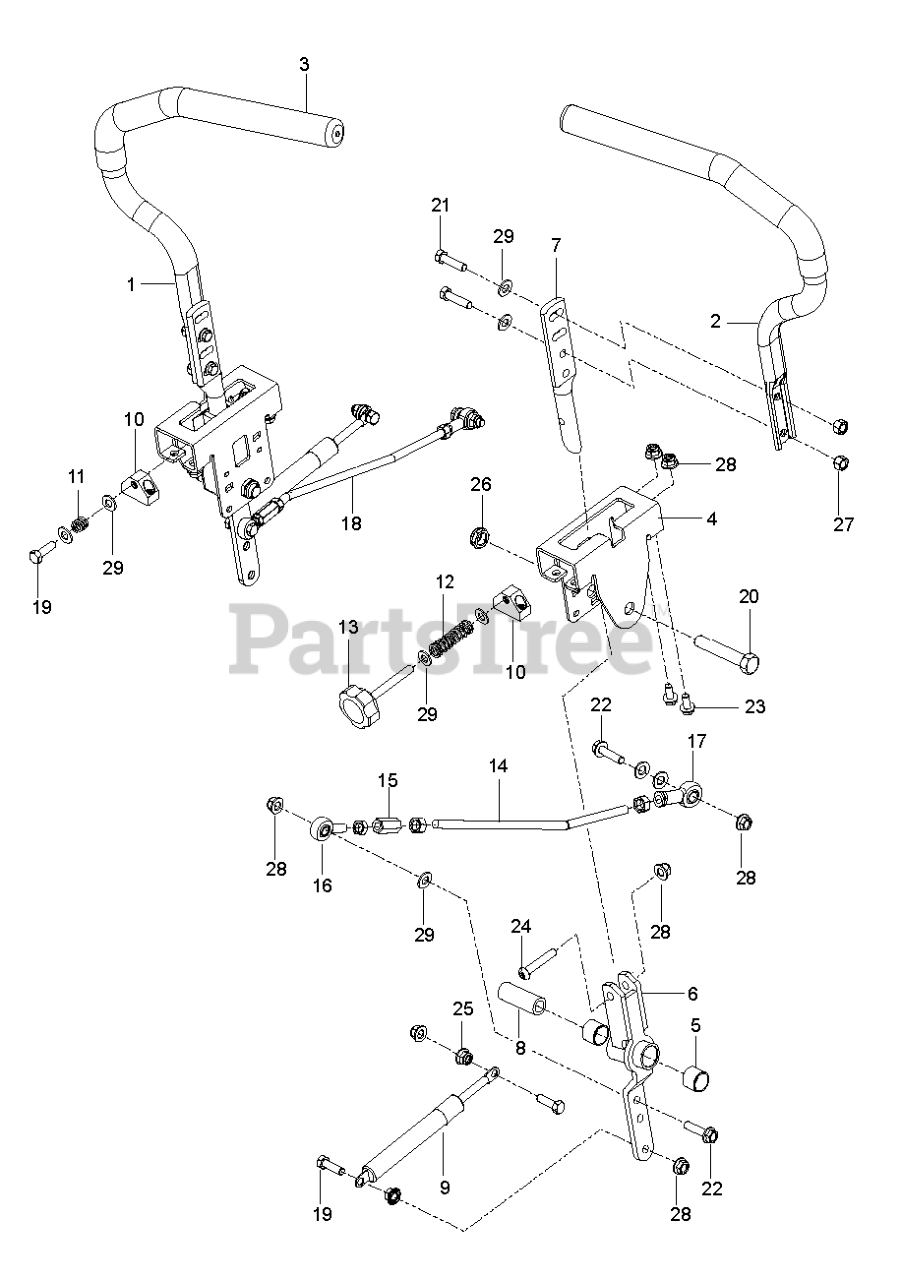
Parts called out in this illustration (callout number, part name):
1	TUBE.LEVER.CONTROL.ZTR.RT.428
2	TUBE.LEVER.CONTROL.ZTR.LT.428
3	GRIP - DRIVE LEVER 12"
4	BRACKET.CONTROLS.ZTR.X431
5	BEARING.PT.750
6	CONTROL.WELDMENT.RZ
7	LEVER.HANDLE MOUNT
8	SPACER.PIVOT.CONTROL
10	BLOCK TRACKING CONTROL ZTR
12	SPRING COMPRESSION 2.0
14	ROD, CONTROL
15	ROD END COUPLER
16	ROD.END.MALE.LH.THREAD
17	JOINT.HEIM.FEML.5/16.RH.THREAD
19	BOLT.5/16-18X1-1/4 FULL.THREAD
20	HCS 1/2-13 X 2-3/4 GD 5 ZD
21	CAPSCREW 5/16 X 1/1/2 HEX HEAD
22	HHFS 5/16-18 X 1.25 TPBLT GD 5
23	HHFS 5/16-18 X 3/4
24	SCREW 5/16-18 X 1 3/4 BTN-HD
25	NUT 5/16C WHIZ
26	NUT 1/2-13 HEX JM NYL
27	NUT 5/16 NYLOC
28	5/16-18 NYLOC FLANGE NUT
29	WASHER
